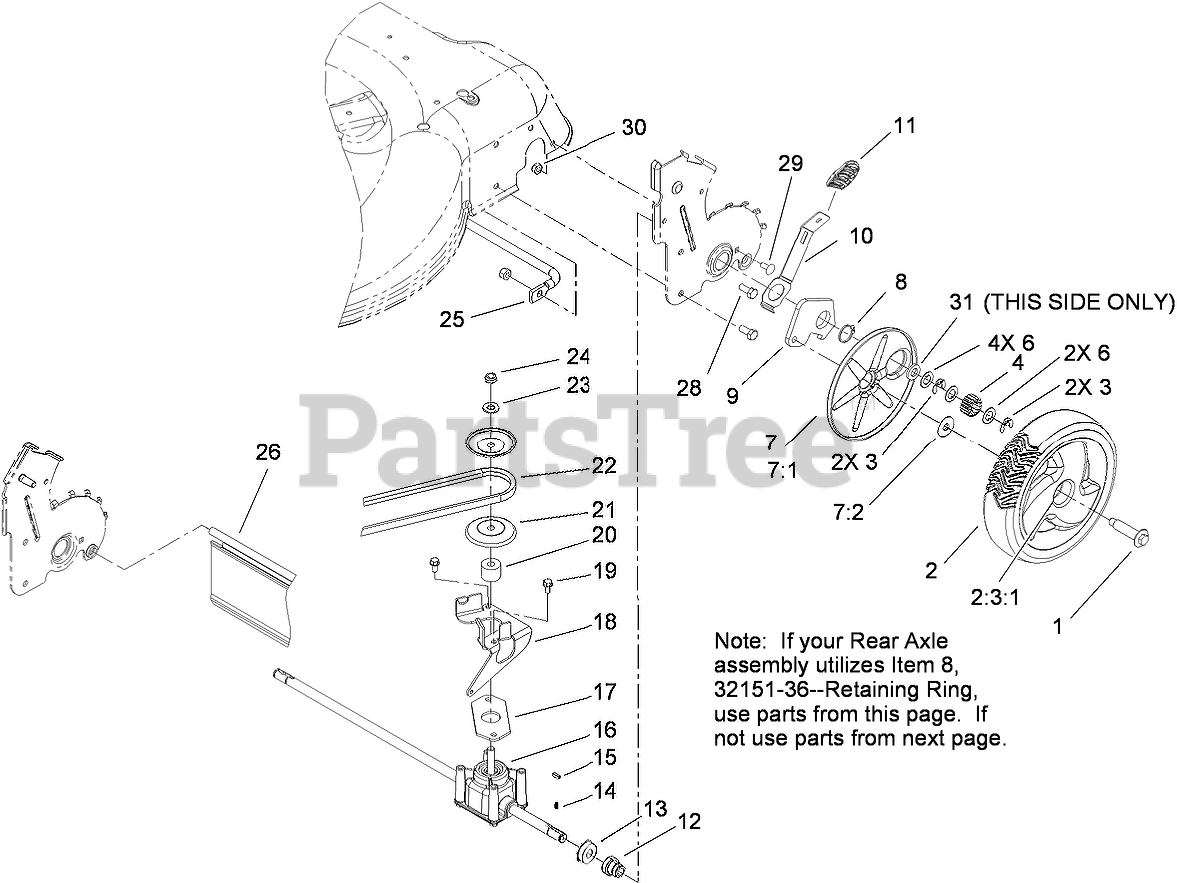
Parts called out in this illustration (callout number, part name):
1	BOLT-SHOULDER
2	Wheel Gear ASM
2:3:1	BUSHING
3	RING-CLIP, LOCKING
4	Gear-Pinion, 15t
6	Washer-Thrust
7	WHEEL COVER ASM
7:1	COVER-WHEEL
7:2	WASHER-STEPPED
8	RING-RETAINING
9	Arm-Pivot, Rear (LH)
10	Arm-Spring
11	Knob-Lever, HOC
12	RETAINER-BEARING, HOC
13	BEARING-BALL
14	SPRING-COMPRESSION
16	TRANSMISSION ASM
17	GASKET-GEARBOX
18	BRACKET-PIVOT
19	SCREW-HWH
20	SPACER
21	PULLEY-HALF
22	BELT-V
23	WASHER-FLAT
24	NUT-HEX
25	BRACE-PLATE, HOC
26	SHIELD-TRAILING
28	SCREW-HH
29	SCREW-CARR
30	NUT-LOCK, NI
31	WASHER-PLAIN
